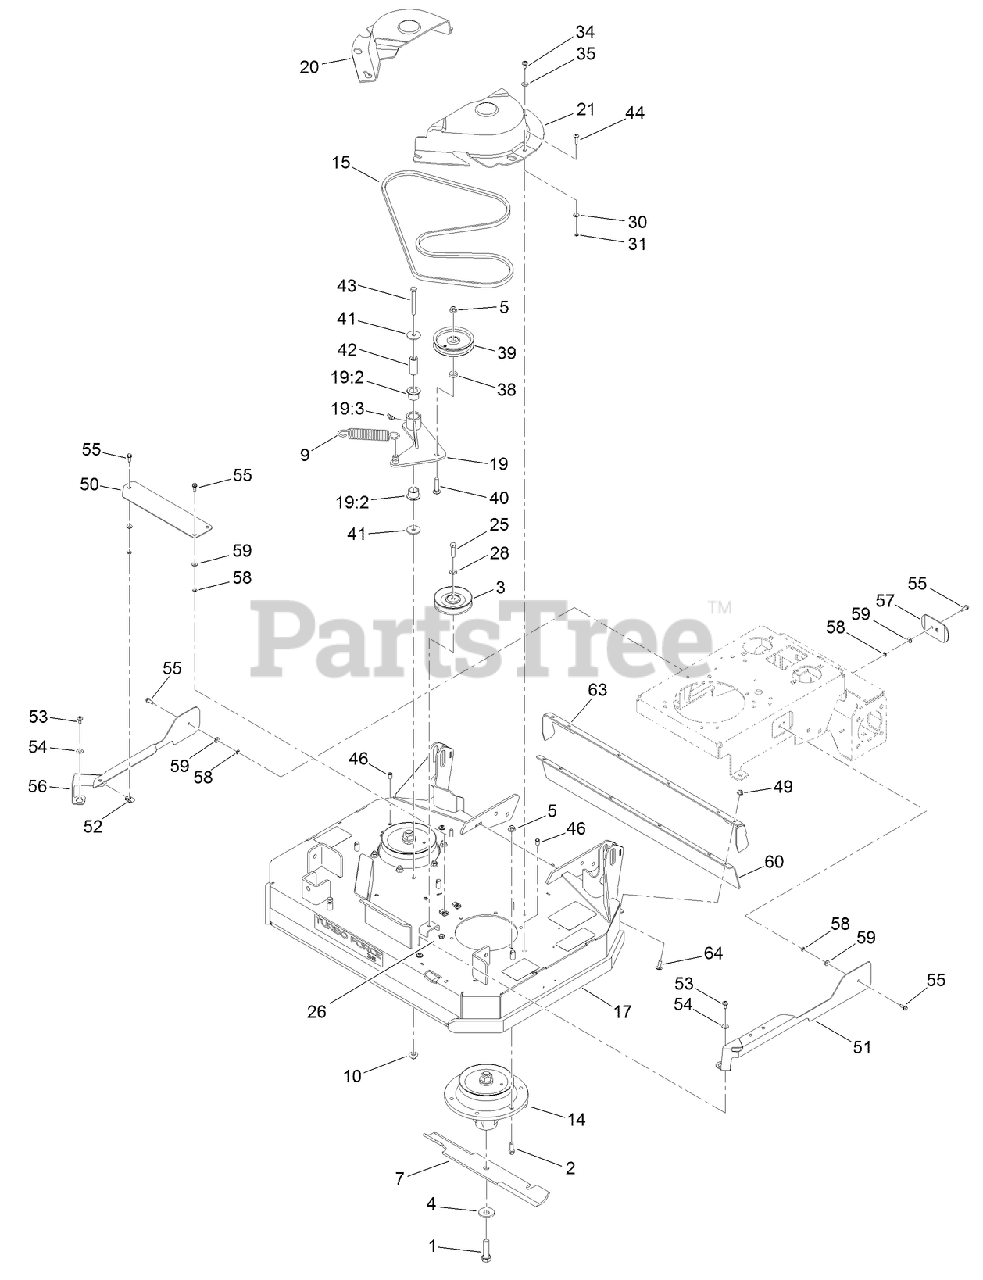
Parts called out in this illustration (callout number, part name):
1	SCREW-BLADE
3	PULLEY-IDLER
4	WASHER-BLADE BOLT, HEAVY
5	NUT-HF, NI
7	BLADE-18IN, HI FLOW
9	SPRING-EXTENSION
10	NUT-FLANGE, NI
14	SPINDLE ASM
15	BELT-V
17	DECK AND DECAL ASM
19	IDLER ARM ASM
19:2	BUSHING
19:3	FITTING-LUBE, 45 DEG
20	COVER-BELT, RH
21	COVER-BELT, LH
25	SCREW-HH
28	WASHER-FLAT
30	WASHER-FLAT
31	NUT-RETAINER
34	SCREW-SHOULDER
35	WASHER-THRUST
38	SPACER
39	PULLEY-IDLER
40	SCREW-CARR
41	WASHER
42	SPACER-PLAIN
43	SCREW-HH
44	SCREW-TTH
46	NUT-CLINCH
49	NUT-HF, NI
50	GUARD-DECK, CENTER
51	GUARD-DECK, LH
53	SCREW-SHOULDER
54	WASHER-THRUST
55	SCREW-HWH, THREAD ROLL
56	GUARD-DECK, RH
57	GUARD-PLATE
58	NUT-RETAINER
59	WASHER
60	FLAP-REAR
63	BRACKET-DEFLECTOR
64	BOLT-CARR
